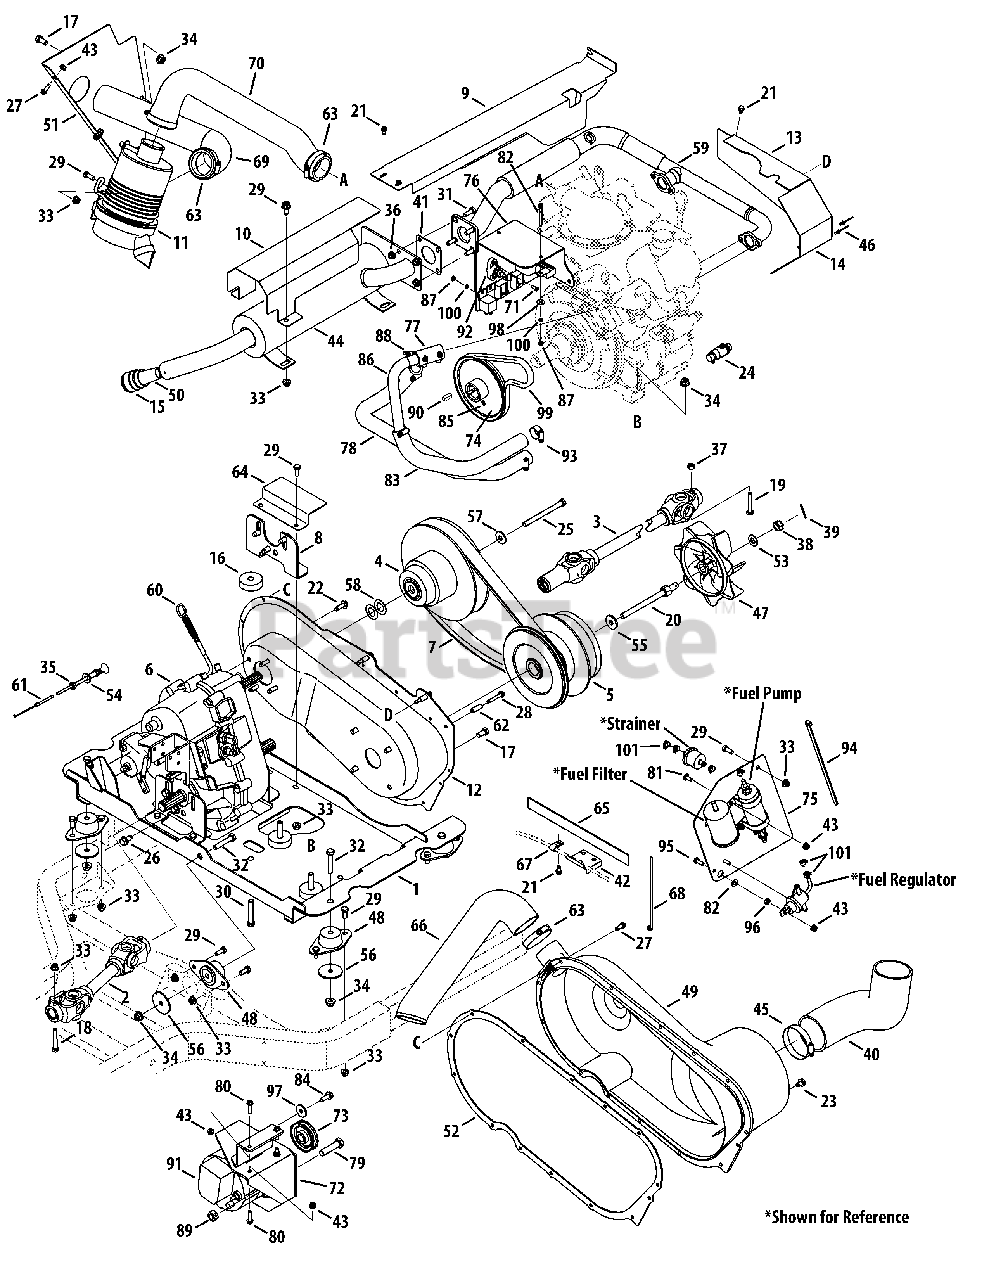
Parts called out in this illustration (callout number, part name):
1	Tray Assembly, Engine, Kohler
2	Shaft Assembly, Rr/prop
3	Shaft Assembly, Frt/prop, Hilliard
4	Clutch Assembly, Cvt, Driven
5	Clutch Assembly, Cvt, Driver, Cvr
6	Case Assembly, Transfer
7	Belt, Cvt, 4x4
8	Bracket, Trans, Mount
9	Cover, Heat, Shield
10	Exhaust, Shield, Heat
11	Filter Assembly, Air Cleaner
12	Cover, Back, Kohler
13	Cover, Eng, Kohler
14	Cover, Engine, Rr, Kohler
16	Spacer, Engine, Kohl
17	Hex Head Screw, 3/8-16, .75
18	Hex Head Screw, 5/16-18, 2.00
19	Hex Head Screw, 5/16-18, 1.875
20	Hex Head Screw, 7/16-20, 5.00
21	Screw, Tt, 1/4-20, 0.500
22	Screw, Tt, 5/16-18, .875
23	Screw, B, 5/16-12, 0.500
25	Hex Head Screw, 3/8-24, 2.50
26	Screw, Tt, 3/8-16, 0.750
27	Screw, Tt, 1/4-20, 0.750
28	Screw, Tt, 1/4-20, 1.625
29	Hex Head Screw, 5/16-18, .75
30	Hex Head Screw, 3/8-16, 2.25
31	Hex Head Screw, 5/16-18, .875
32	Hex Head Screw, 3/8-16, 2.00
33	Nut, Flange Lock, 5/16-18, Nylon
34	Nut, Flange Lock, 3/8-16, Nylon
35	Nut, Jam, 3/8-24
36	Nut, Flange Lock, 5/16-18
37	Nut, Hex Lock, 5/16-18, Ctrlk
38	Nut, Hex, 1/2-20, Gr5, Slot
39	Pin, Cotter, 3/32, 1.0
40	Tube, Cvt, Intake
41	Gasket, Engine
42	Bracket, Cable Shield
43	Nut, Flange Lock, 1/4-20
45	Clamp, Hose, Adj.
46	Rivet, Pop, .125 Od, #42
47	Impeller, Blower
48	Compression Mount, Eng, Head
49	Cover, Cvt
50	Spark Arrester Screen
52	Seal, CVT, Cvr
53	Washer, Flat, .510 x 1.00 x .060
54	Washer, Flat, .406 x .875 x .059
55	Washer, Flat, .450 x 1.250 x .164
56	Washer, Flat, .38 x 2.00 x .12
57	Washer, Bell, .396 x 1.140 x .095
58	Washer, Flat, .793 x 1.368 x .025
59	Pipe, Exhaust, Kohl, EFI
60	Cable, Throttle Control, Kohler
61	Cable, Choke Control, Kohler
62	Spacer, .260 Id x .375od x 1.0l
63	Clamp, Hose
64	Shield, Harness
65	Heat Shield Sleeve
66	Hose, CVT, Exhaust
67	Clamp, Hose
68	Tie, Cable
69	Hose, Air, Inlet
70	Hose, Air, Intake
71	Screw
72	Support, Asm, Alternator, Kohler
73	Pulley, 2.65 OD x 3L
74	Pulley, 6.00 OD x 1.125
75	Bracket, Fuel System, Kohler EFI
76	Bracket, Electrical, Kohler EFI
77	Hose, Rdtr, Top Rear
78	Hose, Rdtr, Lower Rear
79	Hex Head Screw, 1/2-13 x 2.00
80	Screw, tt, 1/4-20 x 1.00
81	Screw, Machine, 1/4-20 x .625
82	Washer, Flat, .25 x .630 x .0515
83	Hose, Radiator
84	Screw, 5/16-18 x .875
85	Screw, 1/4-20 x 3/8
86	Tube, Rdtr
87	Nut, Hex, #10-32
88	Fitting, Petcock
89	Nut, Hex Lock, 1/2-13
90	Square key, 1/4 x 1.50lg
91	Alternator, Aux, 65 Amp
92	Electric Power Distribution Post
93	Clamp, Hose, Adj
94	Tie, Cable
95	Screw, Machine, 1/4-20 x .750
96	Nut, Hex, 1/4-20
97	Washer, Flat, .344 x 1.125 x .12
98	Washer, Flat, .194 x .62 x .063
99	Belt, V-Type
100	Washer, Lock
101	Clamp, Hose, .490 Dia.
